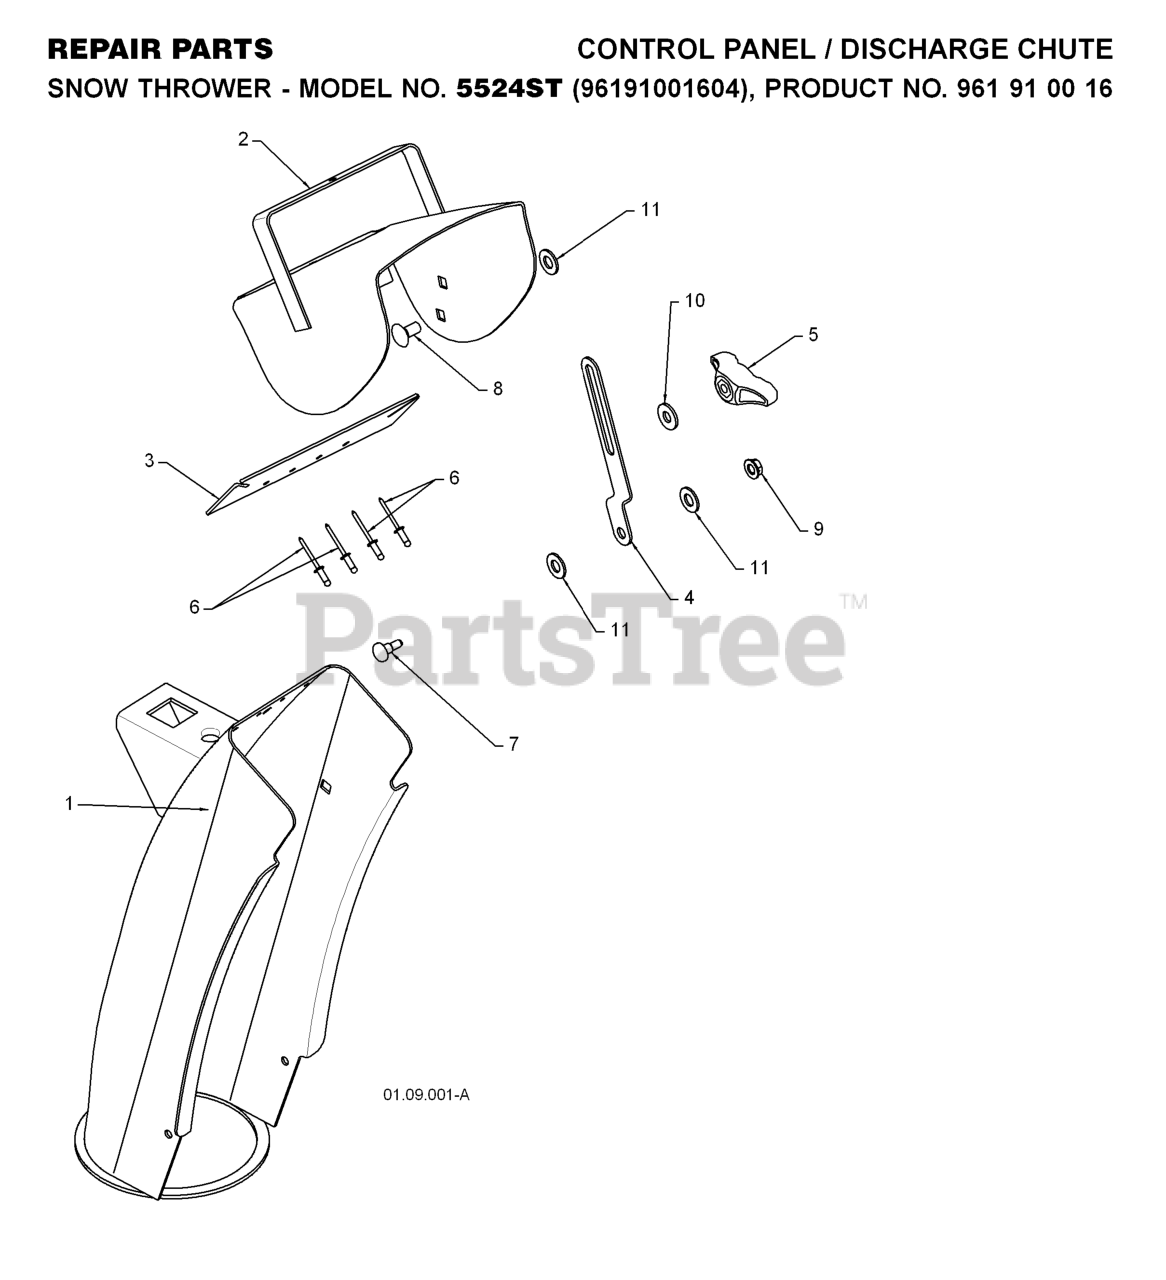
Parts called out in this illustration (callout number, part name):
1	CHUTE ASSEMBLY
2	DEFLECTOR.WELDMENT.PNT.ORANGE
3	SEAL.DEFLECTOR
4	STRAP, CHUTE
5	HNDL.KNOB.GRAY
6	RIVET BLIND
7	SHOULDER BOLT
8	BOLT
9	NUT.HEX.FLANGE.1/4
10	WASHER.20X8.5
11	WASHER, NYLON FRICTION
